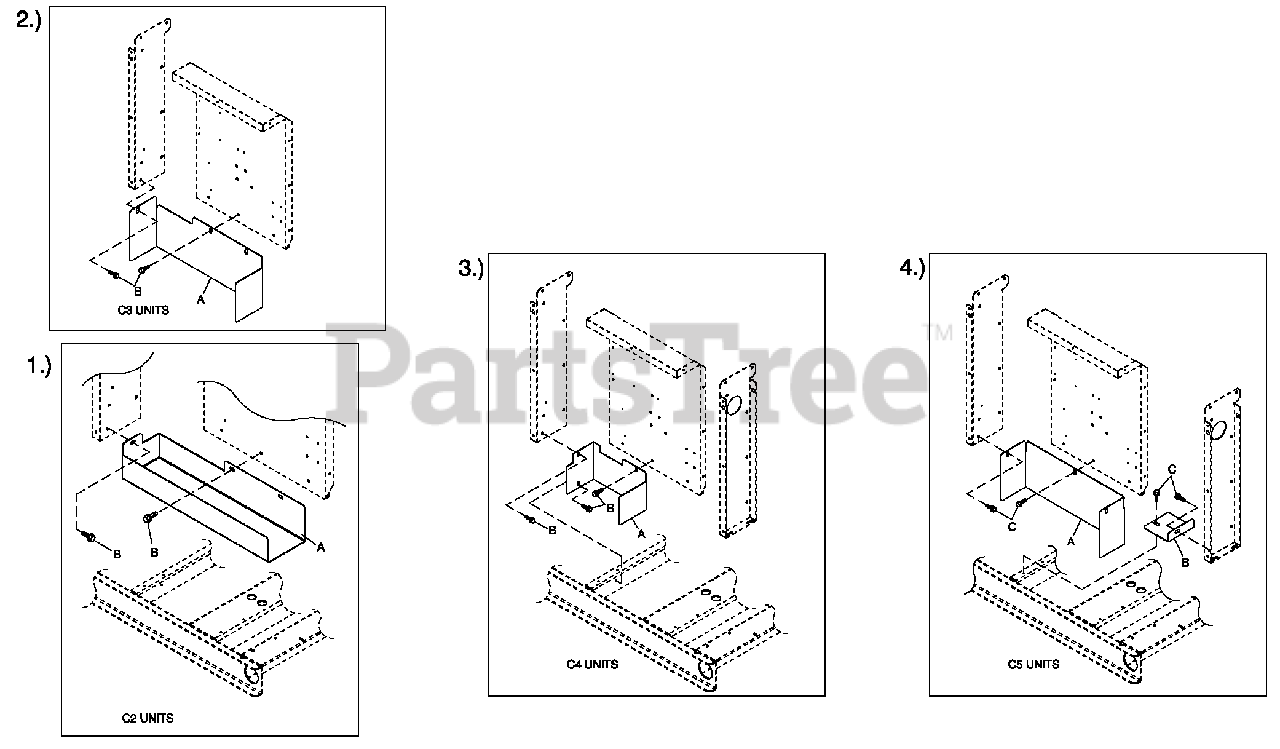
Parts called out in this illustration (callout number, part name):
1	C2 UNITS
2	C3 UNITS
3	C4 UNITS
4	C5 UNITS
A	SHIELD CONN BOXC2
B	SCREW THF M6-1 X 16 N WA Z/JS
A	SHIELD CONTROL STAND C3
A	SHIELD CONTROL STAND C4
A	SHIELD CONTROL STAND C5
B	SHIELD CONTROL STAND C5
C	SCREW THF M6-1 X 16 N WA Z/JS
